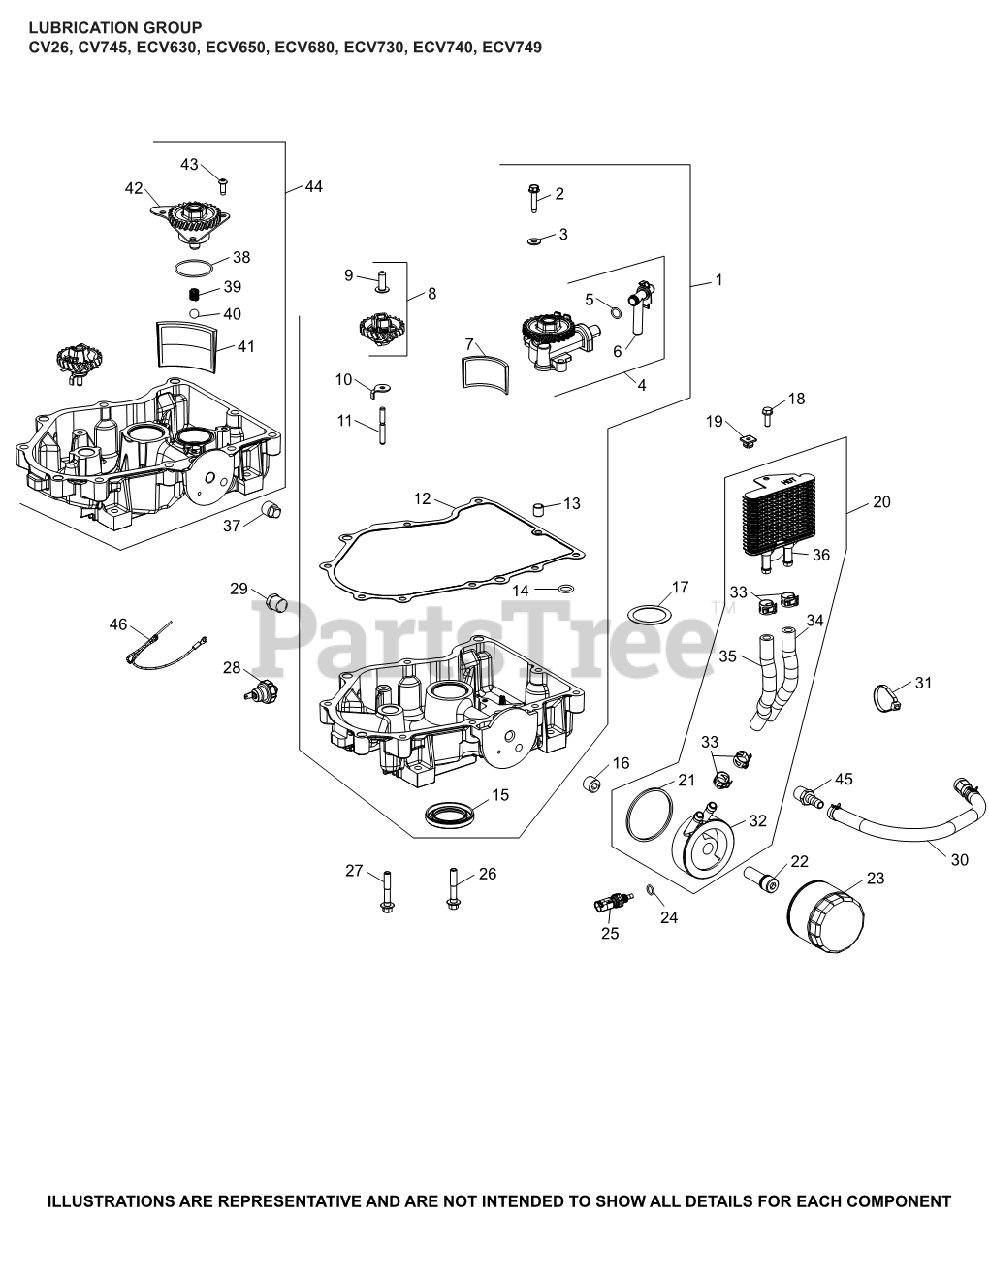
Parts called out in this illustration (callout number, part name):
8	KIT, GOVERNOR GEAR W/PIN
9	PIN, GOVERNOR REGULATING
10	TAB, LOCKING
11	SHAFT, GOVERNOR GEAR
12	GASKET, OIL PAN
15	SEAL, OIL
16	PLUG, PIPE CTSK 3/8"
22	NIPPLE, OIL FILTER
23	OIL FILTER
27	SCREW, FLG M8X1.25X45
28	SENSOR, OIL PSI
29	PLUG, HD PIPE 3/8"
38	O-RING (1.78" DIA)
39	SPRING, COMPRESSION
40	PRESSURE RELIEF BALL
41	SCREEN, OIL
42	PUMP, OIL ASSEMBLY
43	SCREW, BUTTON HEAD
44	KIT, OIL PAN ASSEMBLY
